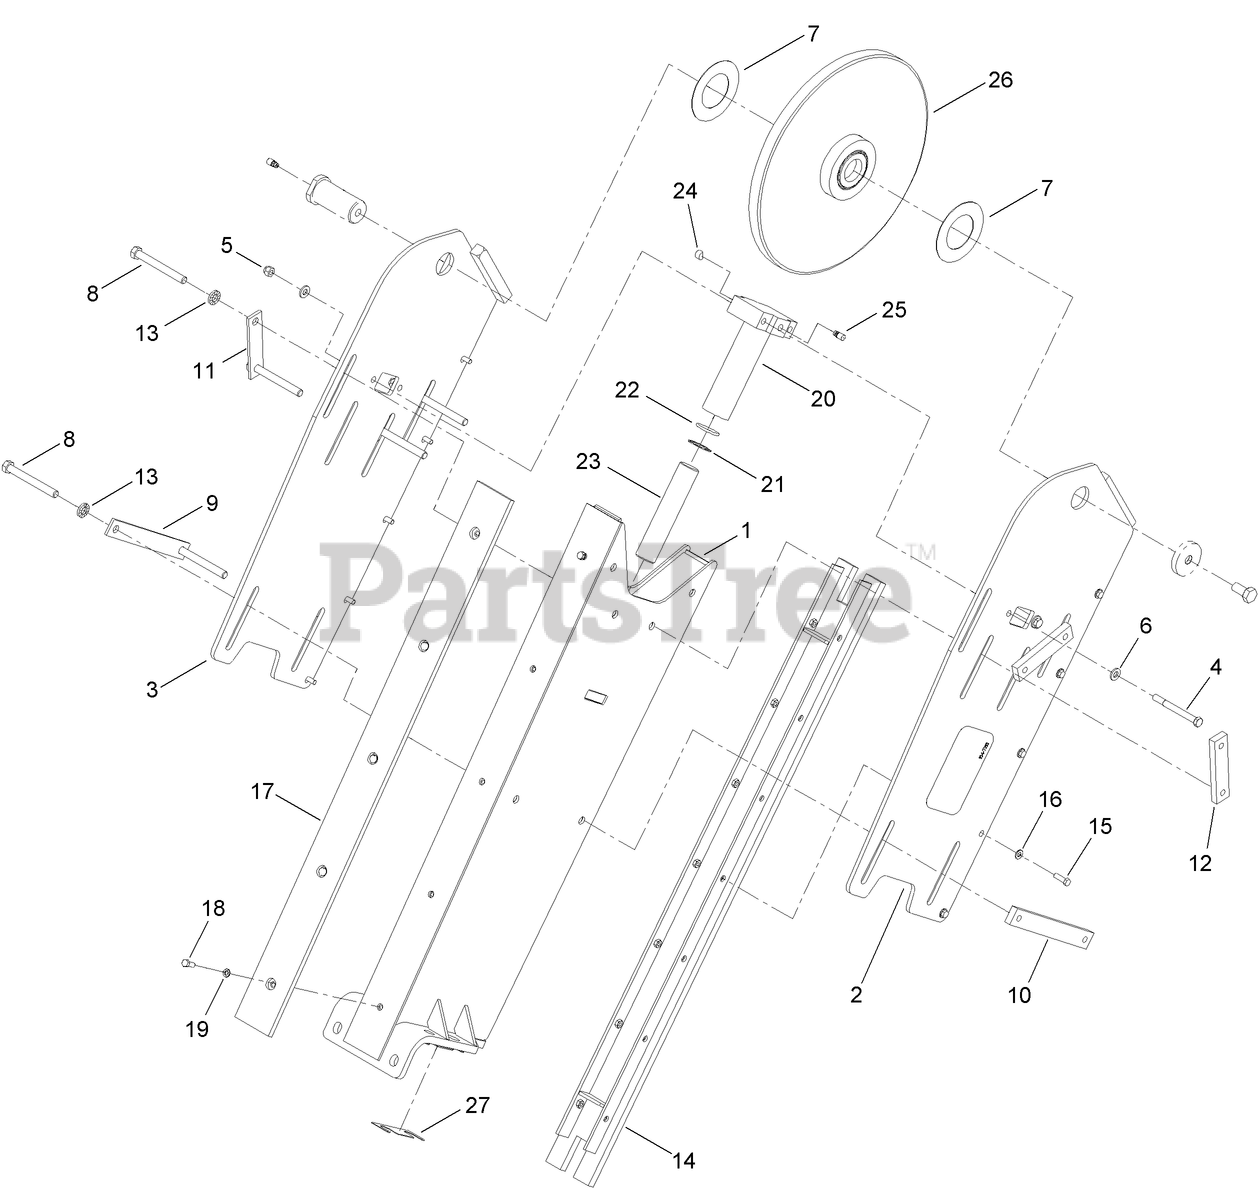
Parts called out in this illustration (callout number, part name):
1	BOOM-ROCK, 5 FOOT
2	LH END BOOM PLATE ASM
3	RH END BOOM PLATE ASM
5	NUT-HEX
7	WASHER-BOOM, END (ROLLER)
8	SCREW-HH
9	BAR-WASHER, LONG
10	BAR-TAPPED, LONG
11	BAR-WASHER, SHORT
12	BAR-TAPPED, SHORT
13	WASHER-LOCK
14	CHANNEL-WEAR PAD, 5 FOOT
15	SCREW-HH
16	WASHER-FLAT
17	BAR-WEAR PAD, 5 FOOT
18	SCREW-HH
19	WASHER-LOCK
20	CYLINDER ASM (BOOM END)
21	WASHER-BACKUP
23	ROD-BOOM, END (CYLINDER)
24	PLUG-BLEED
25	FITTING-LUBE, STRAIGHT
26	BOOM END ASM
